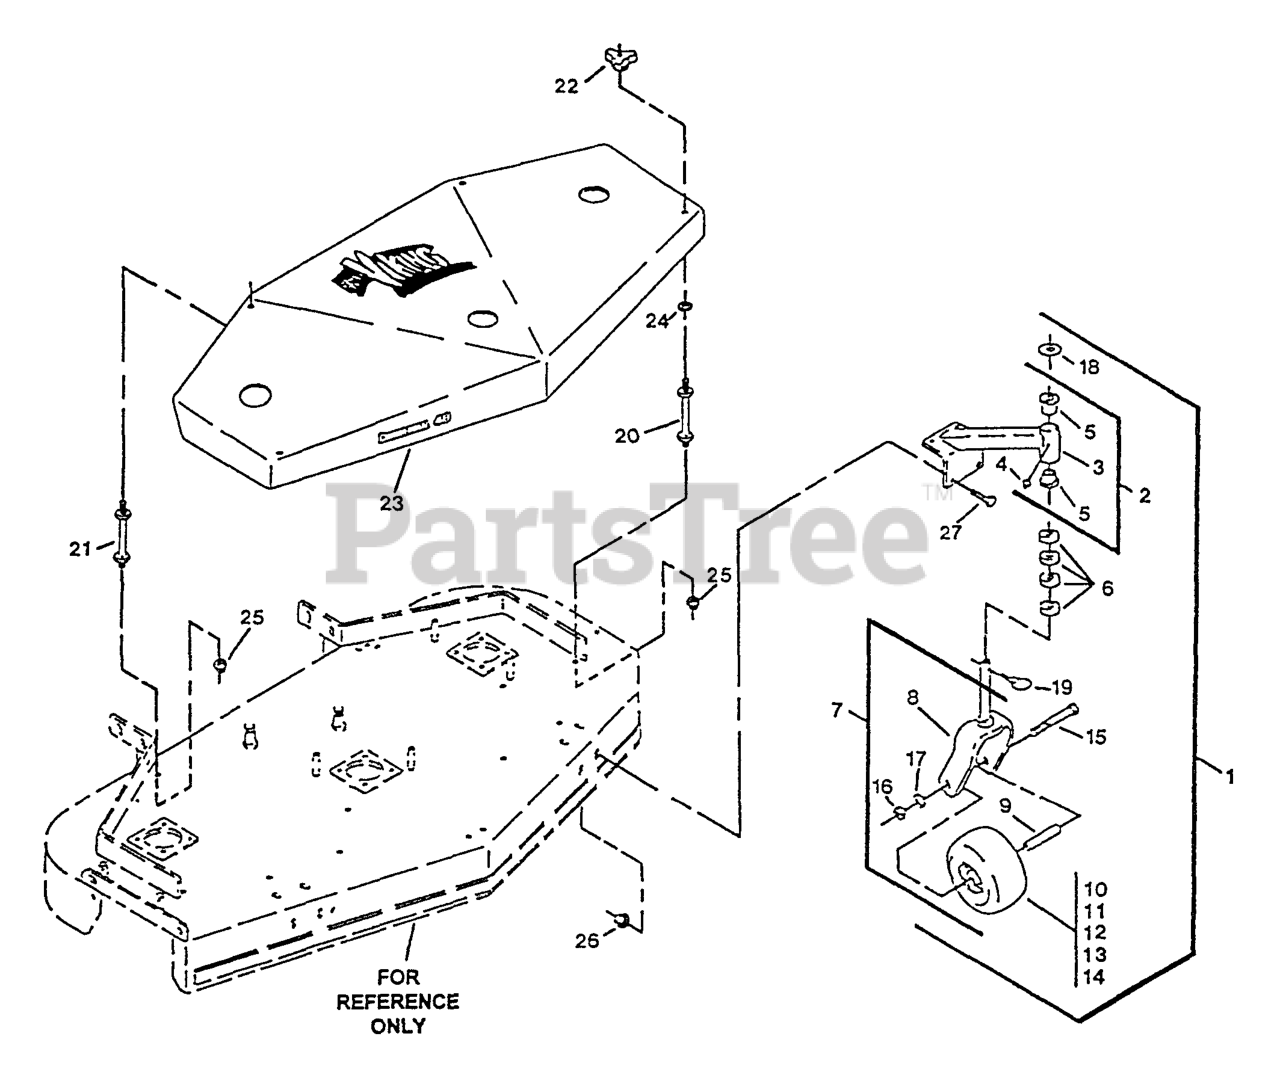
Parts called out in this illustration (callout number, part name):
1	CASTER/MOUNT ASM
2	SUPPORT ASM
5	BEARING-FLANGED
6	SPACER-CASTER
13	BEARING
14	BUSHING
18	WASHER-FLAT
20	STUD-SHIELD, BELT (SHORT)
21	STUD-SHIELD, BELT (LONG)
22	KNOB-3 PRONG
